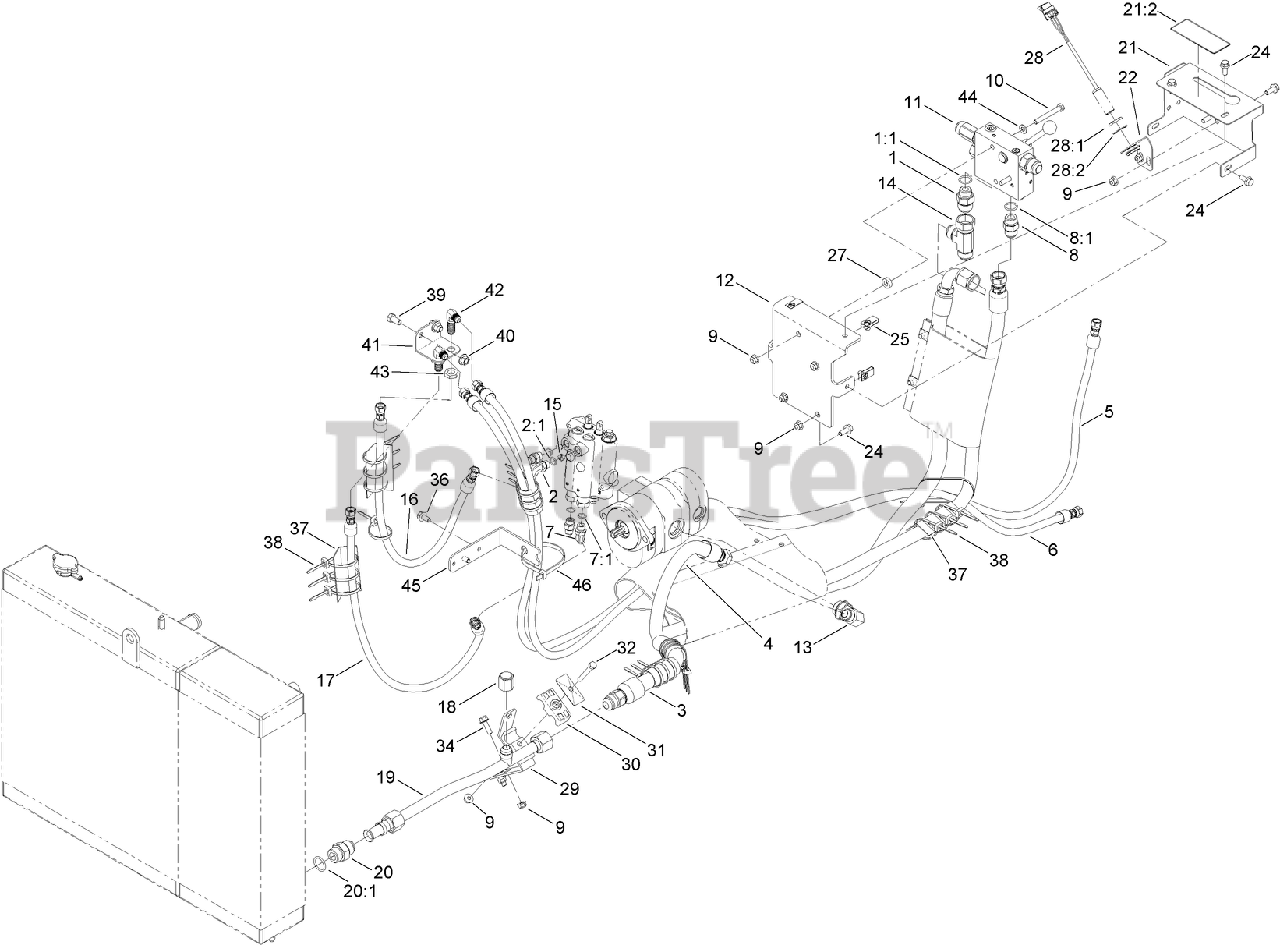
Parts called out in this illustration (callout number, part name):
1	FITTING-STRAIGHT
1:1	O-RING
2	FITTING-ELBOW, 90 DEG
2:1	O-RING
3	HOSE ASM
4	HOSE ASM
5	HOSE ASM
6	HOSE ASM
7	FITTING-ELBOW, 45 DEG
7:1	O-RING
8	FITTING-STRAIGHT
8:1	O-RING
9	NUT-HF, NI
10	SCREW-HH
11	VALVE-CONTROL, VIBE PLOW
12	PLATE-VALVE, PLOW
13	ADAPTOR-ELBOW
14	FITTING-TEE
15	ORIFICE
16	HOSE ASM
17	HOSE ASM
18	FITTING-CAP
19	HYD TUBE ASM
20	FITTING-STRAIGHT
20:1	O-RING
21	COVER PLATE ASM
21:2	DECAL-VIBE PLOW CONTROL
22	PLATE-SENSOR
24	SCREW-HHF
25	NUT-U TYPE
27	SPACER
28	PROXIMITY SWITCH ASM
28:1	NUT-HEX
28:2	WASHER-LOCK, INTERNAL TOOTH
29	BRACKET-TUBE
30	CLAMP-TUBE
31	PLATE-COVER
32	SCREW-HH
34	SCREW-HHF
36	SCREW-HHF
37	PROTECTOR-HOSE
38	TIE-CABLE
39	SCREW-HH
40	NUT-HF, NI
41	PLATE-BULKHEAD
42	UNION-BULKHEAD, ELBOW 90
43	NUT-LOCK, BULKHEAD
44	WASHER-PLAIN
45	BRACKET-HOSE
46	TIE-CABLE
